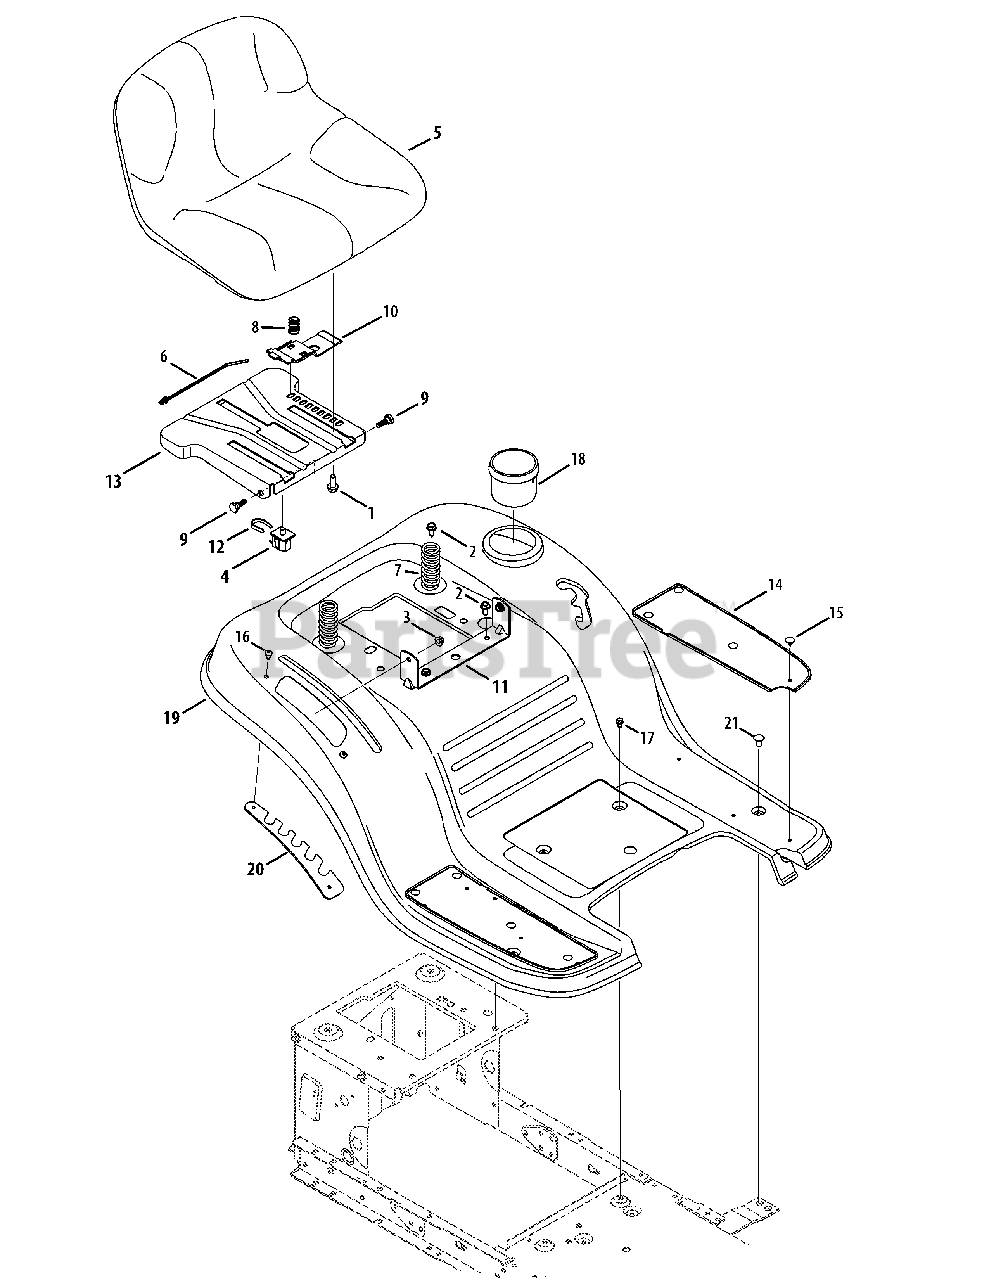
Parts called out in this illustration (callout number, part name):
1	Hex Flange Bolt, 3/8-16 x .875
2	Screw, Hd. Tapp, 5/16-18 x .75
3	Flange Lock Nut, 5/16-18
4	Seat Safety Switch
5	Seat
6	Push Mount Cable Tie
7	Spring, Compress., 1.28 x 3.125
8	Spring, Compress., .68 x 1.065 x .055
9	Shoulder Screw, 5/16-18 x .437 x .268
10	Seat Adjustment Lever
11	Seat Pivot Bracket
12	Switch Retainer Clip
13	Seat Mounting Bracket
14	Rubber Foot Pad, LH
14	Rubber Foot Pad, RH
15	Ratchet Clip, .250
16	Tap Screw, 1/4-20 x .5
17	Screw Pan Torx Head, 1/4-20 x .500
18	Cup Holder
19	Fender
20	Lift Adjuster Bracket
21	Carriage Screw, 1/4-20 x .62
